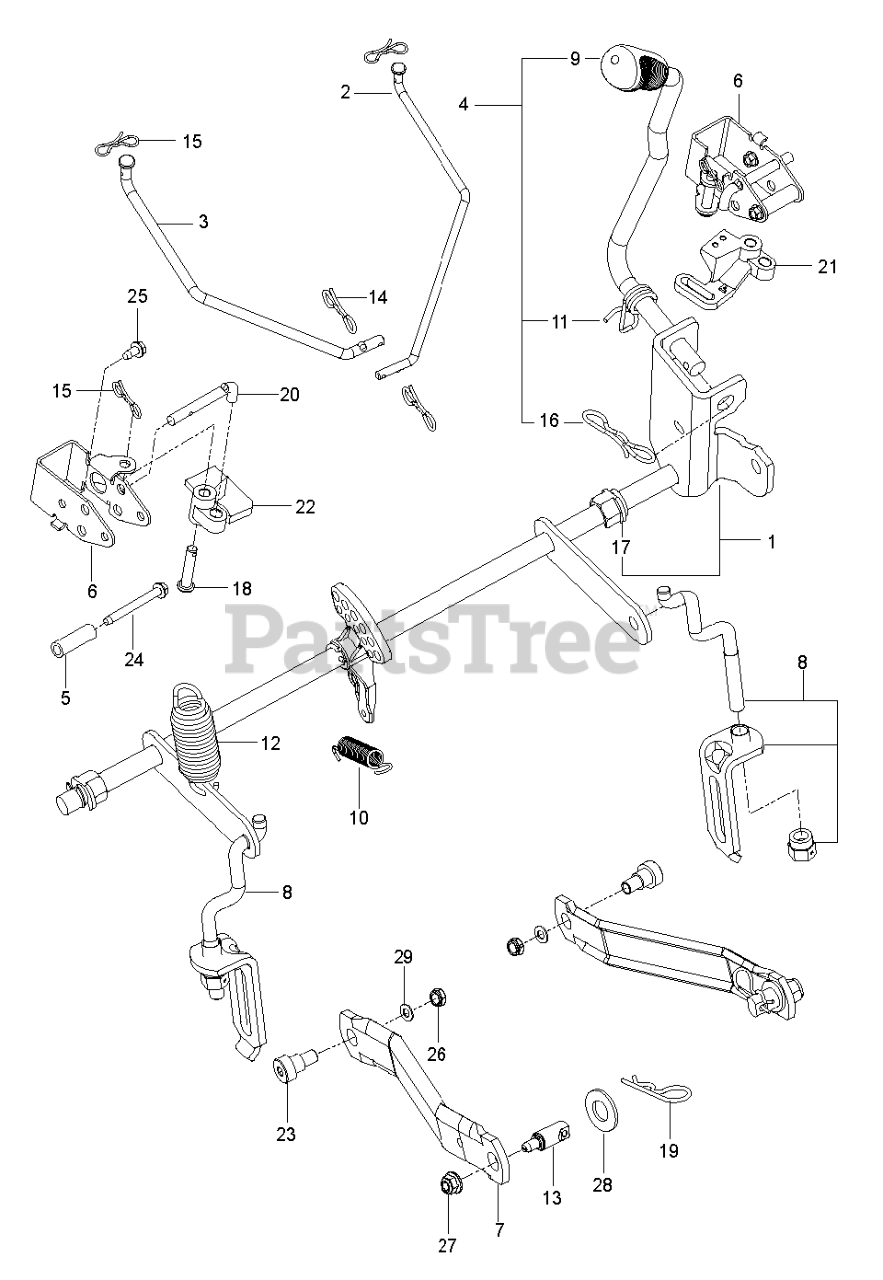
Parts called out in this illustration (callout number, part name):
1	SHAFT.ASM.RZ.DECK.LIFT.SRV
2	LINK.BRAKE.PARK.UPPER.LH
3	LINK.BRAKE.PARK.UPPER.RH
4	LIFT.LEVER.ASM.RZ.SERVICE
5	SPACER.334.ID.5.OD.1.5.L
6	BRACKET.BELLCRANK.PBRAKE X431
7	ARM.SUSPENSION.MOWER
8	LINK.ASM.RZ.LIFT.SERVICE
9	GRIP.HANDLE.LIFT.PVC.BLACK
10	RETURN.BRAKE.PARK.AUTO
11	SPRING.TORSION.LIFT.HANDLE
13	STUD.FASTNER.W/ANTI-ROTATE
14	PIN.COTTER.5/16.BOW TI
15	PIN COTTER;LOCKING;BOWTIE;1IN
16	PIN.COTTER.7/16.BOW TI.
17	PLASTIC NUT
18	PIN.5.16X1.5
19	HAIRPIN #4
20	ROD.PUSH.BRAKE
21	BELLCRANK.LH
22	BELLCRANK.RH
23	SB 3/8-16 X 3/8 SKT HD ZD
24	SCREW THD;ROLL;1/4-20 X 2.25
25	SCREW.1/4-20X5/8
26	NUT HEX 3/8-16 NYLON, THIN
27	5/16-18 NYLOC FLANGE NUT
28	WASHER
29	WASHER
